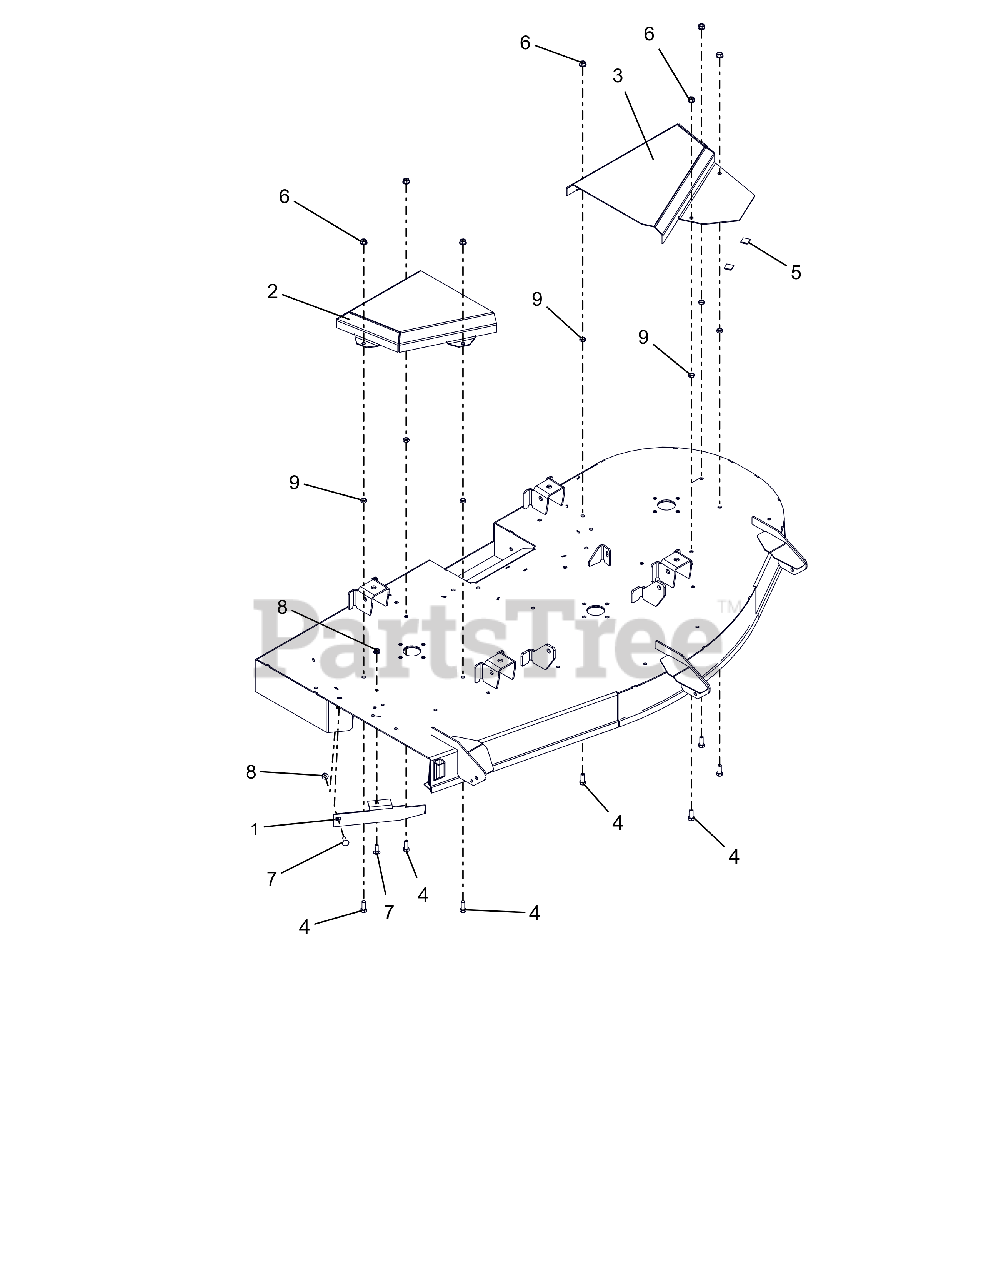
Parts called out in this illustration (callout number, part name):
1	BAFFLE, DISCHARGE 60
2	COVER, RH BELT 60
3	COVER, LH BELT 60
4	BLT,HEX .38-16X1.00 G5 ZCC
6	NUT-LK-TOP-FLG .38-16 ZC120
7	BLT,RHSN .31-18X1.00 G5 ZCC
8	NUT,LK-NYL-FLG .31-18 G5ZC120
9	NUT-JAM .375-16 G2 ZCC
